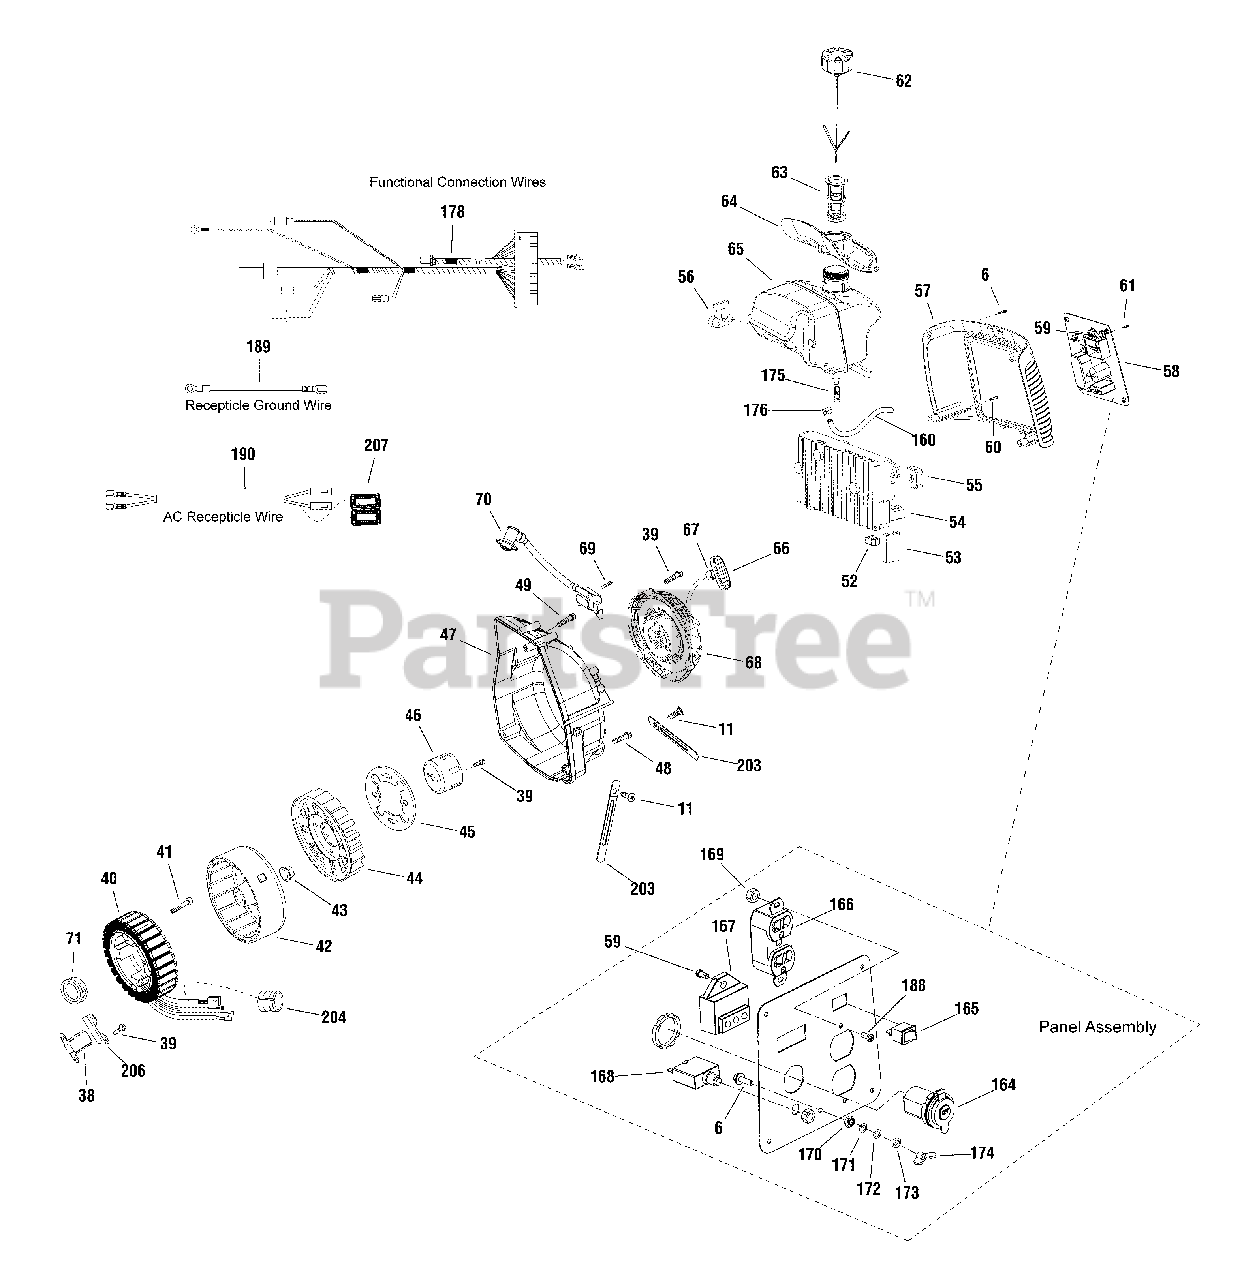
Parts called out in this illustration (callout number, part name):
11	BOLT
38	TRIGGER, Ingition
45	TERMINAL
47	COVER-FAN
48	BOLT
49	BOLT
52	MOUNT, Vibration
53	MOUNT, Vibration
55	MOUNT, Vibration
56	MOUNT, Vibration
59	SCREW
60	SCREW
61	SCREW
63	FILTER, Filler Neck
67	GRIP
68	STARTER, Rewind
69	SCREW
71	SEAL, Oil
167	LIGHT, Indicator
168	BREAKER, Circuit
169	NUT
170	NUT
171	WASHER
172	WASHER
173	WASHER
174	NUT
175	FILTER, Fuel Tank
176	CLAMP
178	HARNESS, Wiring
188	SCREW
190	HARNESS, Wiring
203	BRACKET
204	COVER, Rubber
206	PROTECTOR BOARD
